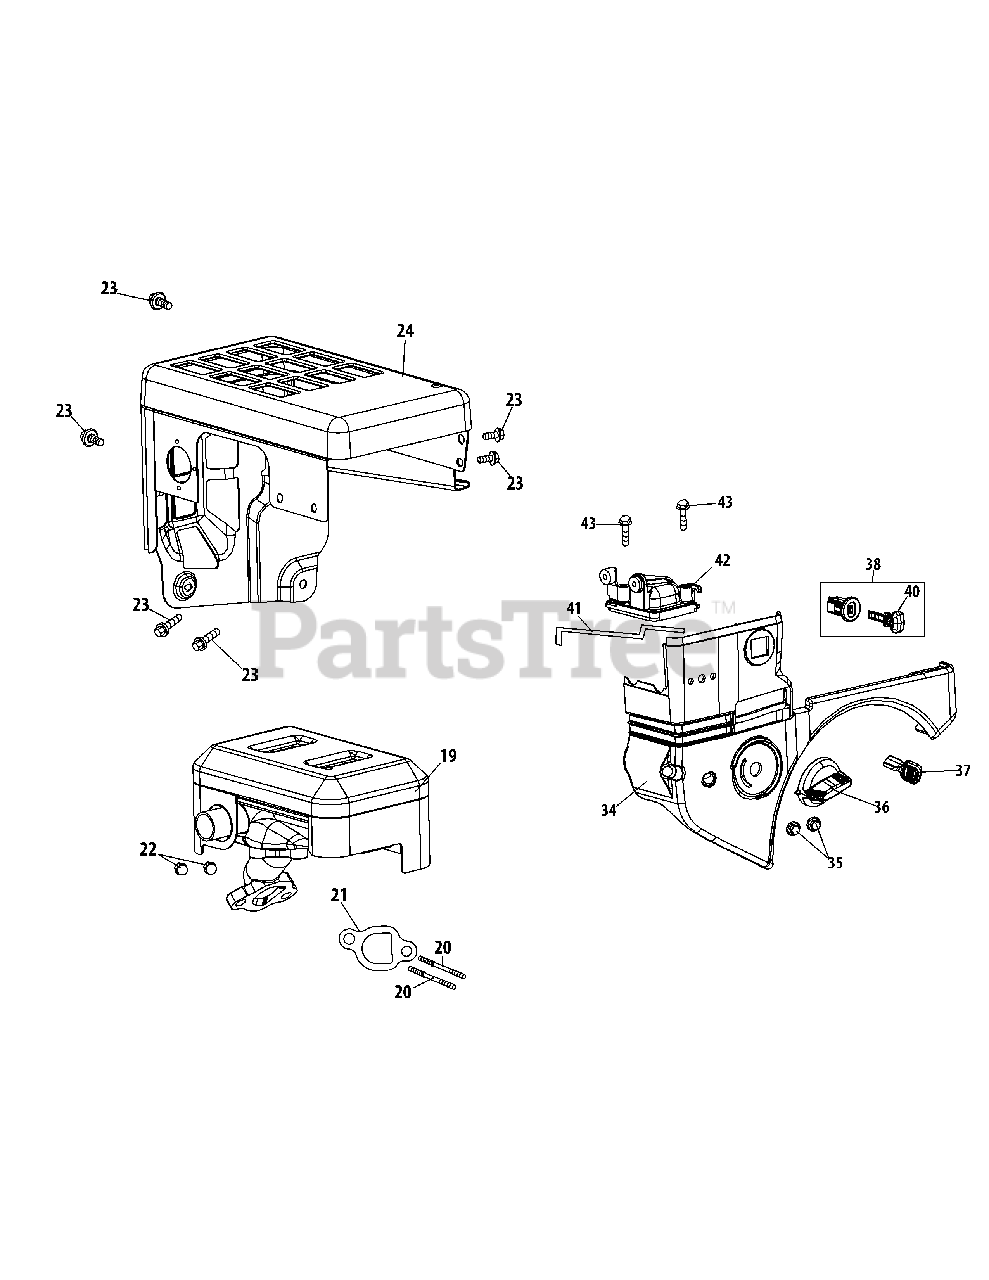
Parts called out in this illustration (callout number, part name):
19	Muffler Assembly
20	Stud M8×36
20	Muffler Stud
21	Exhaust Pipe Gasket
22	Nut, M8
23	Bolt M6×12
24	Muffler Shield
34	Air Cleaner Housing
36	Choke Knob
37	Throttle Control Knob
38	Key Switch Assembly
40	Key
41	Choke Linkage
42	Heater Box
43	Bolt M6×28
